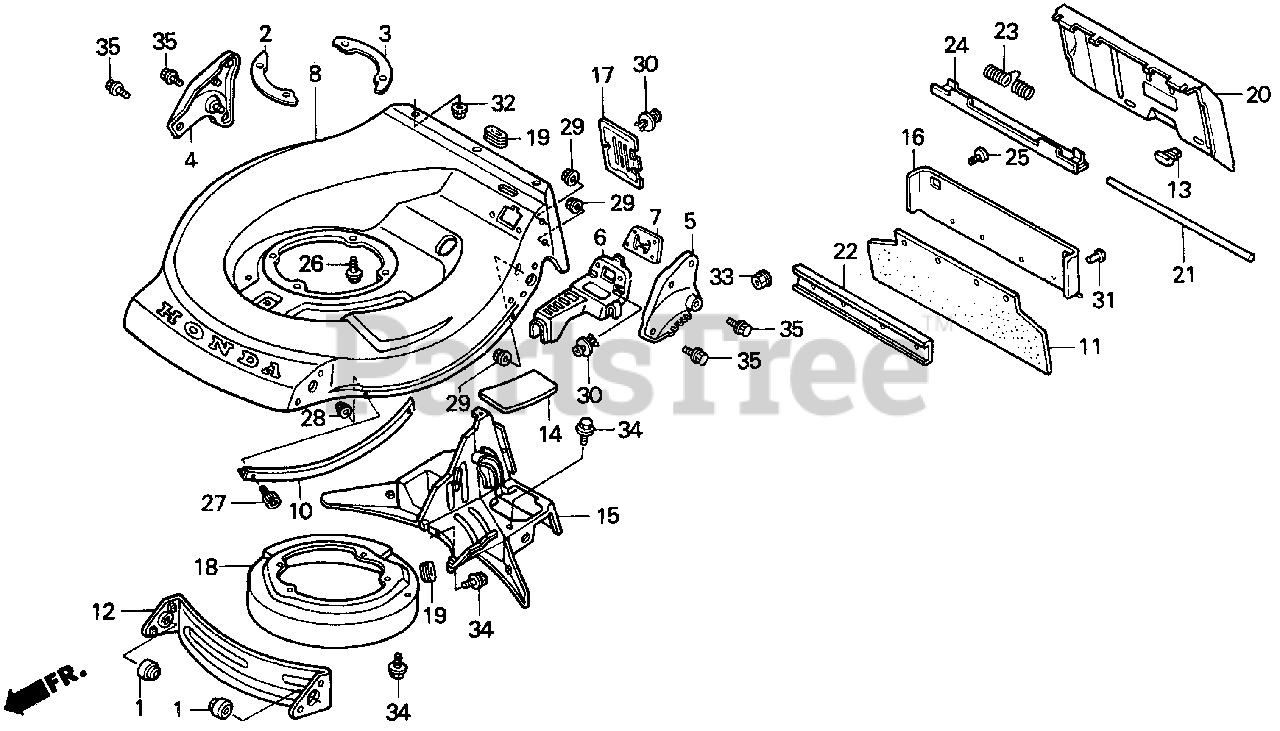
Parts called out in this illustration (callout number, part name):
1	DUST SEAL A
2	SPACER, ENGINE (A)
3	SPACER, ENGINE (B)
4	STAY, R. HANDLE
5	STAY, L. HANDLE
6	COVER, CHANGE
7	GROMMET, COVER
8	DECK SET, MOWER
8	HOUSING, CUTTER *NH190M* (VINTAGE GRAY METALLIC)
10	GUARD, HOUSING
11	SHIELD, SAFETY
12	SCROLL, FR.
13	STOPPER, DISCHARGE GUARD
14	STEP, FOOT
15	SCROLL, RR.
16	PLATE, RR. SCROLL
17	COVER, RR.
18	COVER, ROTO-STOP
19	GROMMET, CABLE
20	GUARD, DISCHARGE
21	SHAFT, HINGE (NOT AVAILABLE)
22	PLATE, DISCHARGE GUARD
23	SPRING, GUARD RETURN
24	PLATE, HINGE
25	BOLT, SPECIAL (9X15)
26	BOLT, ENGINE SETTING
27	BOLT, HEX. SOCKET (6X12)
28	NUT, NYLON RING (6MM)
29	NUT, FLANGE (8MM)
30	CLIP, RR. CORNER (BLACK)
31	RIVET, SAFETY SHIELD (4.8MM)
32	NUT, FLANGE (6MM)
33	NUT, FLANGE (8MM)
34	BOLT, FLANGE (6X12) Use up to Engine SN 1543277.
35	BOLT, FLANGE (8X14)
